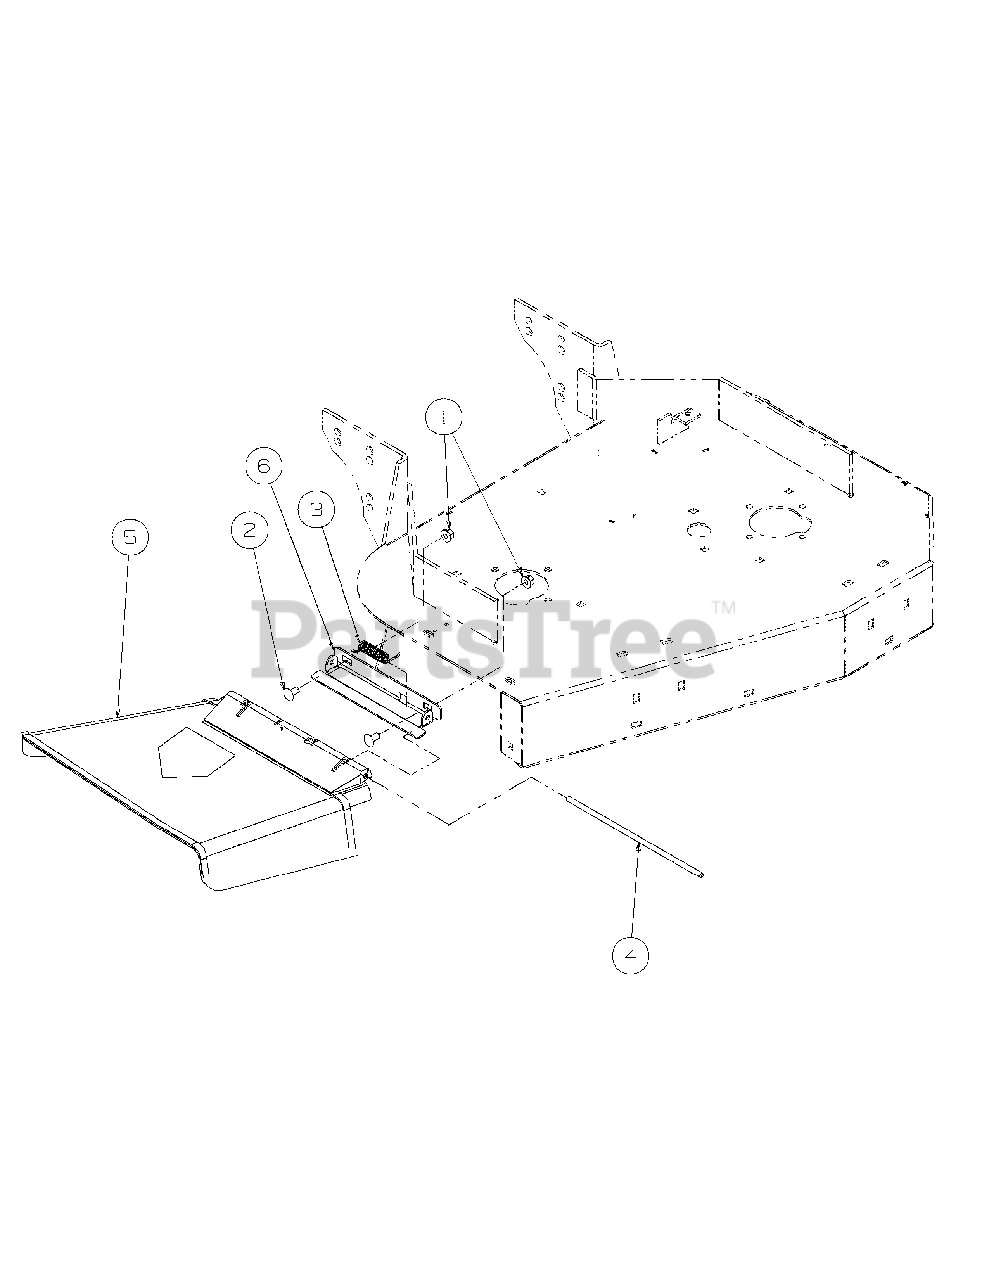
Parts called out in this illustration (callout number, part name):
1	Hex Nut, 3/8-16, Flange Lock
2	Carriage Bolt 3/8-16 x 1.00
3	Torsion Spring
4	Chute Deflector Rod
5	Deflector Chute
6	Deflector Chute Bracket
